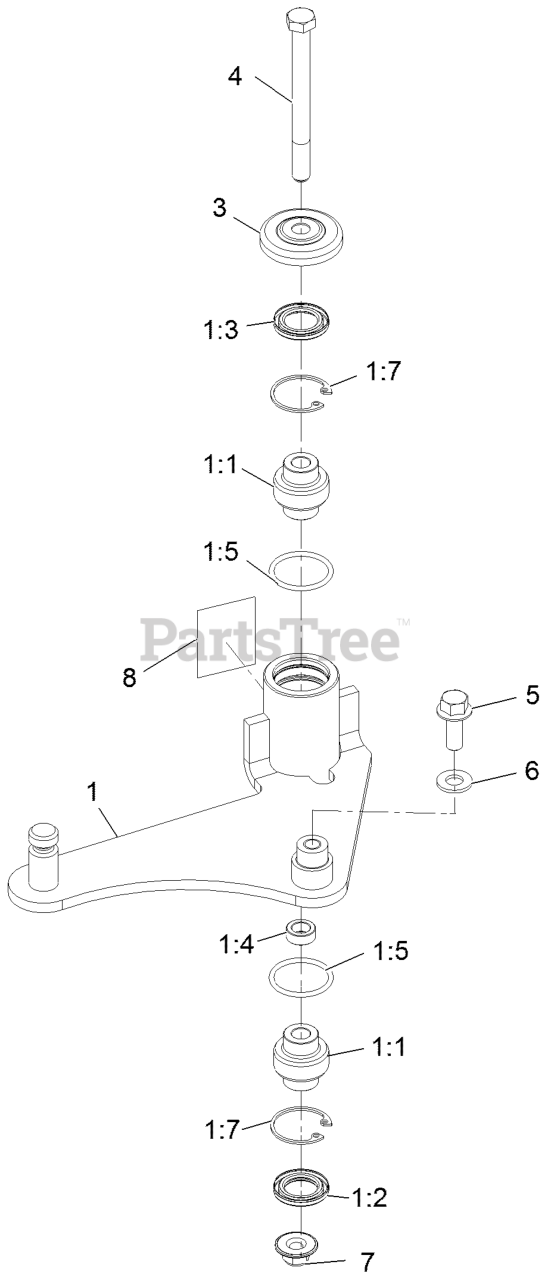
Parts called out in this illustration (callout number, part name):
1	ASM,Deck Idler
1:1	BEARING-SPHERICAL
1:2	SEAL-LIP, DOUBLE
1:3	SEAL-LIP, SINGLE
1:7	RING-SNAP
3	GUARD-TOP
4	SCREW-HH
5	SCREW-HHF
6	WASHER-FLAT
7	Nut-Nyloc 3/8-16 Flg
8	DECAL,GREASE
